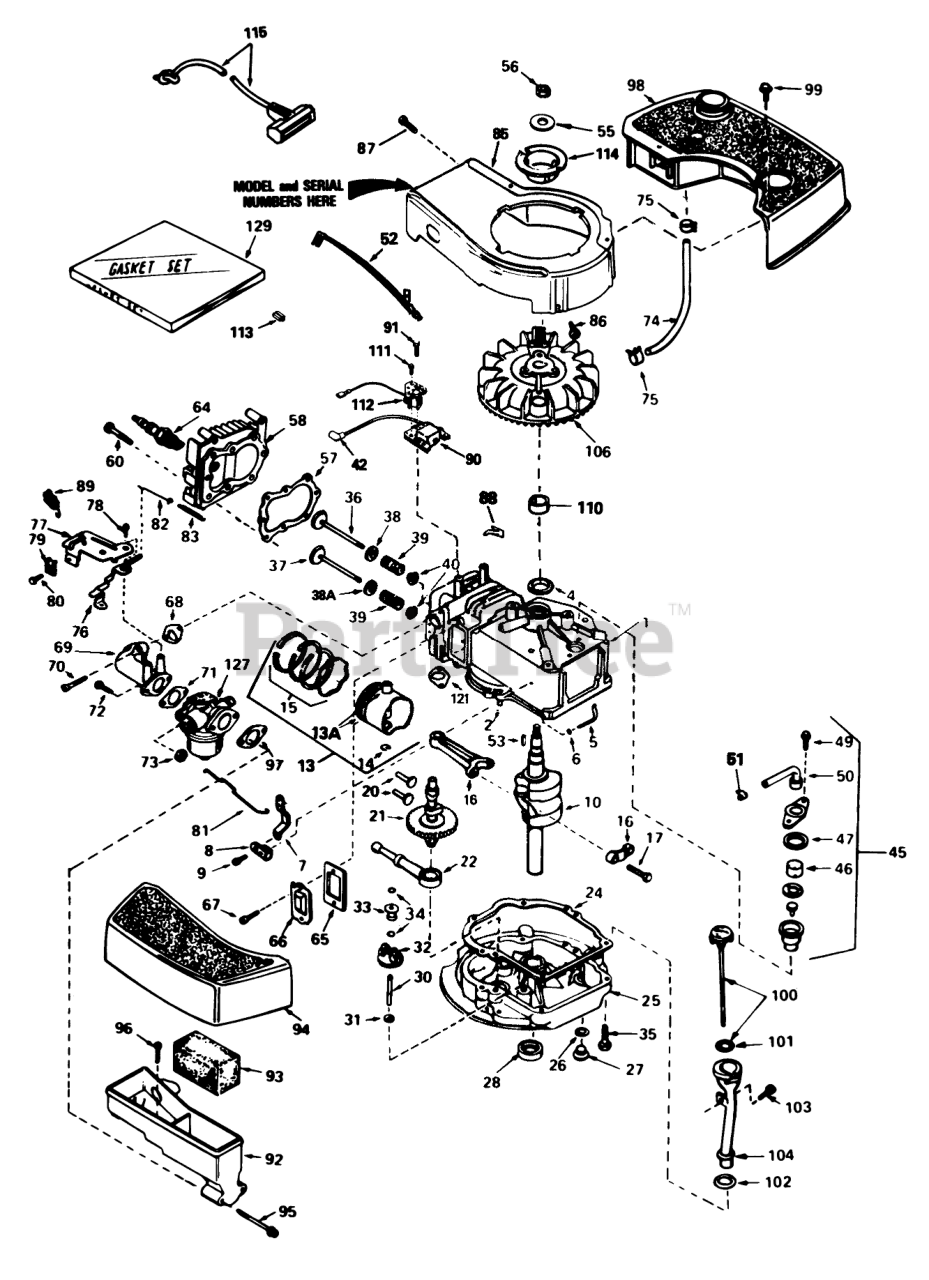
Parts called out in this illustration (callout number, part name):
1	Cylinder Assembly (Incl. Ref. #2 & 4)
2	Pin-Dowel
4	Seal-Oil
5	Rod-Governor (Incl. Ref. #6)
6	Washer-Flat
7	Governor Lever
8	Clamp-Lever, Governor
9	Screw
10	Crankshaft
13	Piston-Pin & Ring Assy. (Std.)(Incl. Ref. #13A, 14 & 15)
13	Piston-Pin & Ring Assembly (.010 oversize)(Incl. Ref. #13A, 14 & 15)
13	Piston-Pin & Ring Assembly (.020 oversize)(Incl. Ref. #13A, 14 & 15)
13A	Piston & Pin Assembly (Std.)(Incl. Ref. #14)
13A	Piston & Pin Assembly (.010 oversize)(Incl. Ref. #14)
13A	Piston & Pin Assembly (.020 oversize)(Incl. Ref. #14)
14	Ring-Retaining, Piston Pin
15	Ring Set (Std.)
15	Ring Set (.020" OS)
15	Ring Set (.010" OS)
16	Rod Assembly-Connecting (Incl. Ref. #17)
17	Bolt-Rod, Connecting
20	Lifter-Valve
21	Camshaft(Mech.Comp. Release)
22	Oil Pump ASM
24	Gasket
25	Flange Assembly-Mounting (Incl. Ref. #26, 27, 28 & 30)
26	Gasket-Oil Drain
27	Plug Oil Drain
28	Seal Oil
30	Shaft-Governor
31	Washer-Flat
32	Gear Assembly-Governor (Incl. Ref. #31)
33	Spool-Governor
34	Ring-Retaining
35	Screw (1/4-20 x 1-1/4)
36	Valve-Intake (Std.)(Incl. Ref. #40)
36	Valve-Intake (1/32" oversize)(Incl. Ref. #40)
37	Valve-Exhaust (Std.)(Incl. Ref. #40)
37	Valve-Exhaust (1/32" oversize)(Incl. Ref. #40)
38	Seal Assy., Intake
38A	Cap-Upper Valve Spring
39	Spring-Valve
40	Cap-Valve, Spring
42	Cover-Spark Plug
45	Breather Assembly (Incl. Ref. #46 thru 51)
46	Element-Breather
47	Gasket-Breather
49	Screw (10-24 x 9/16)
50	Tube, Breaker
51	Clip, Breather
52	Wire-Ground
53	Key-Flywheel
55	Washer-Belleville
56	Nut-Flywheel
57	63573 GIL 42 SNWTHW
58	Head-Cylinder
60	Screw (5/16-18x1-1/2)
64	Spark Plug-Resistor (R J19 L M)
65	Gasket-Breather
66	Cover-Valve
68	Gasket-Intake
69	Pipe-Intake (Incl. Ref. #68)
70	Screw (1/4-20 x 1)
71	Gasket-Carburetor
72	Screw (1/4-28 x 7/8)
73	Nut and Lock Washer (1/4-28)
74	Line-Fuel
75	Clamp-Line, Fuel
76	Lever Control
77	Control Assembly-Speed (Incl. Ref. #76, 78 & 89)
78	Screw, Hex Washer Hd Shoulder Self-Tap
79	Conduit
80	Screw (10-32 x 3/8)
81	Link-Throttle
82	Link Governor Spring
83	Spring Governor
85	Housing Blower
86	Screw (1/4-20x19/32)
87	Screw (10-24 x 9/16)
88	Clip-Wire
89	Terminal
90	Solid State
91	Screw
92	Body Air Cleaner
93	Filer, Air
94	Cove, Air Cleaner
95	Screw Fil Hd.
96	Screw, Hex Washer Hd Shoulder Self-Tap
97	Gasket-Air Cleaner
98	Tank-Fuel
99	Screw (10-32 x 35/64)
100	Dipstick-Oil (Incl. Ref. #101)
103	Screw (10-32 x 1/2)
104	Tube-Oil Fill
106	Flywheel
111	Screw (8-32x27/64)
112	Coil, Alternator
113	Terminal
114	Hub-Starter
115	Rope Assy., Starter
121	Gasket Exhaust
127	Carburetor (Incl. Ref. #71)
129	Gasket Set
